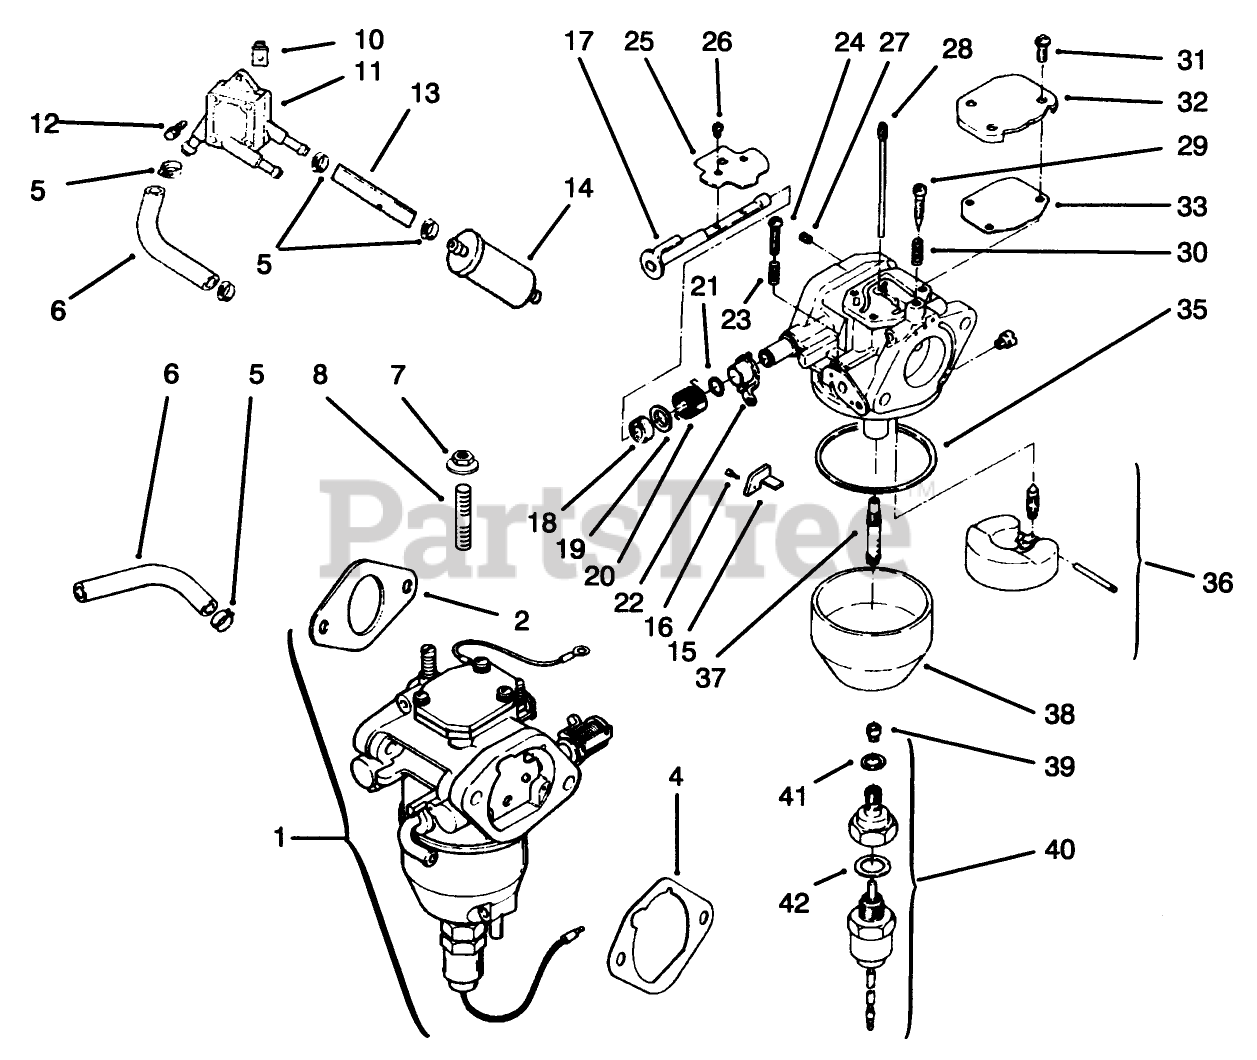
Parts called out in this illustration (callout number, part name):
2	Gasket-Carburetor (Only On: 72103)
4	Gasket-A/C Base (Only On: 72103, 72083)
5	Clamp
6	Line-Fuel 10 1/2" (Only On: 72103, 72083)
8	Stud M6x1.0x95 (Only On: 72103, 72083)
11	Pump-Fuel
13	Line-Fuel 3 1/2" (Only On: 72103)
14	Filter-Fuel (Only On: 72042,72043,72062,72063)
15	Bracket-Throttle Stop (Only On: 72103, 72083)
16	Screw M2.5X45X5.5 (Only On: 72103)
17	Shaft-Choke (Only On: 72103, 72083)
18	Washer (Only On: 72103, 72083)
19	Collar-Choke (Only On: 72103, 72083)
20	Spring-Choke Return (Only On: 72103, 72083)
21	Ring-Choke Lever (Only On: 72103)
22	Lever-Choke (Only On: 72103)
23	Spring-Throttle Screw (Only On: 72103, 72083)
24	Screw-Throttle Adjust (Only On: 72103, 72083)
25	Valve-Choke
26	Screw-Throttle Shaft (Only On: 72103, 72083)
27	Jet-Air Bleed (Only On: 72103)
28	Jet-Slow (Only On: 72103)
29	Screw-Idle Adjust (Only On: 72103, 72083)
30	Spring-Idle Adjust Screw (Only On: 72103)
31	Screw (Only On: 72103)
32	Cover-Passage (Only On: 72103, 72083)
33	Gasket-Passage Cover (Only On: 72103, 72083)
35	Gasket-Float Chamber (Only On: 72103)
36	Kit-Float Repair (Only On: 72103)
37	Nozzle-Main (Only On: 72103,72083)
38	Chamber-Float (Only On: 72103)
39	Jet-Main (Only On: 72103)
40	Kit-Solenoid INC 41-42 (Only On: 72103, 72083)
41	Gasket-Chamber Screw (Only On: 72103)
42	Gasket-Solenoid (Only On: 72103, 72083)
